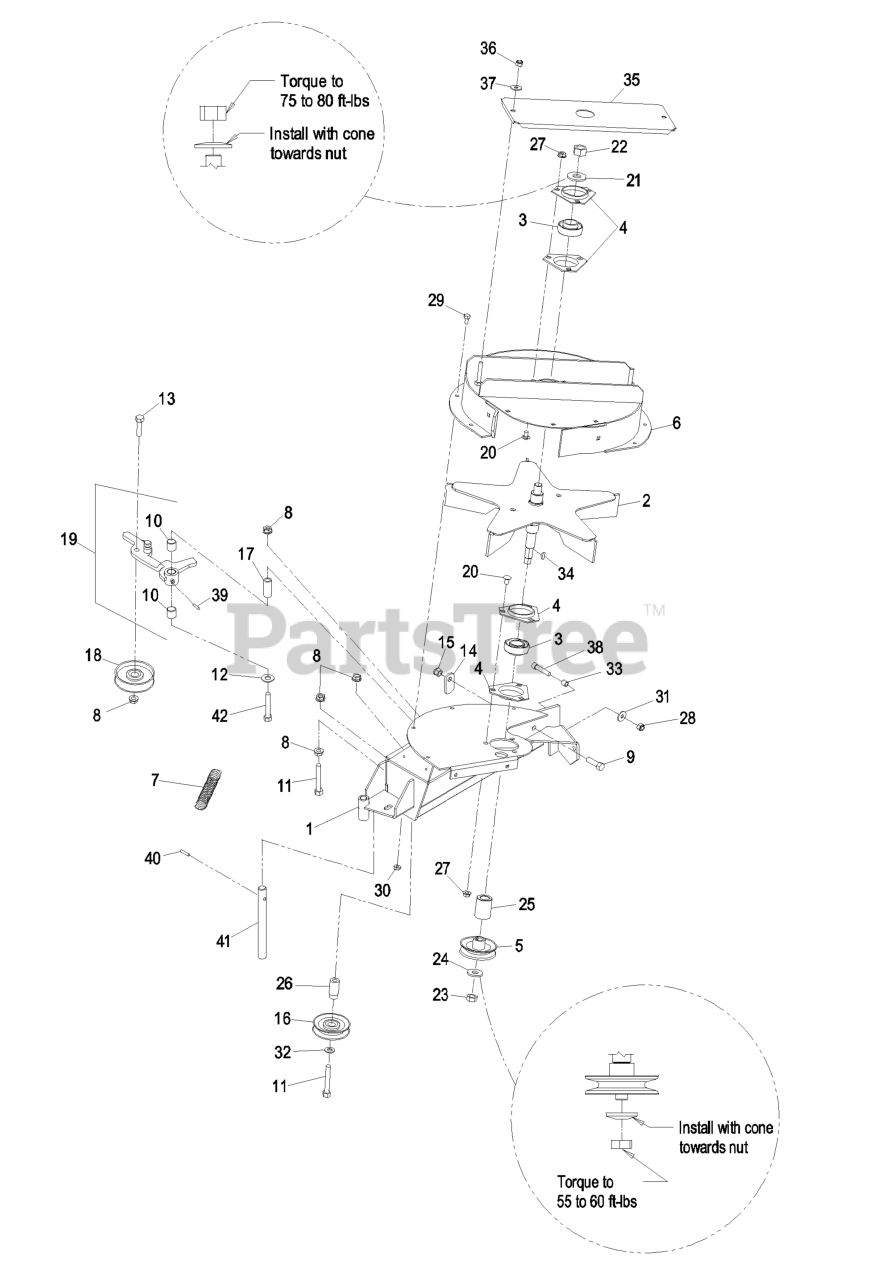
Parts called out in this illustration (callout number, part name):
1	WLD, BLOWER MOUNT
2	IMPELLER
3	BEARING
4	HOUSING-FLANGE
5	SHEAVE-BLOWER
6	ASM,UPPER HOUSING
7	SPRING-IDLER
8	NUT-HHF, WHIZ
9	SCREW-HH
10	BUSHING
11	BOLT-CARR
12	WASHER-FLAT
13	SCREW-HH
14	LATCH-CATCHER, GRASS
15	NUT-LOCK, NI
16	IDLER-INSIDE
17	BUSHING-PIVOT, IDLER
18	IDLER-FLAT
19	ASM, IDLER ARM - SERVICE
20	SCREW-CARR
21	WASHER-SPRING
22	NUT-HEX
23	NUT-JAM
24	WASHER-SPRING
28	NUT-HEX
29	SCREW-HH
31	WASHER-SPRING
32	WASHER-FLAT
33	BUSHING, LOCATOR
34	KEY-WOODRUFF
35	ASM, BEARING COVER
36	NUT-LOCK, NI
37	WASHER-FLAT
38	SCREW-HSH
39	FITTING-GREASE
40	PIN-ROLL
41	SHAFT-CATCHER, GRASS
42	SCREW-HSBH
